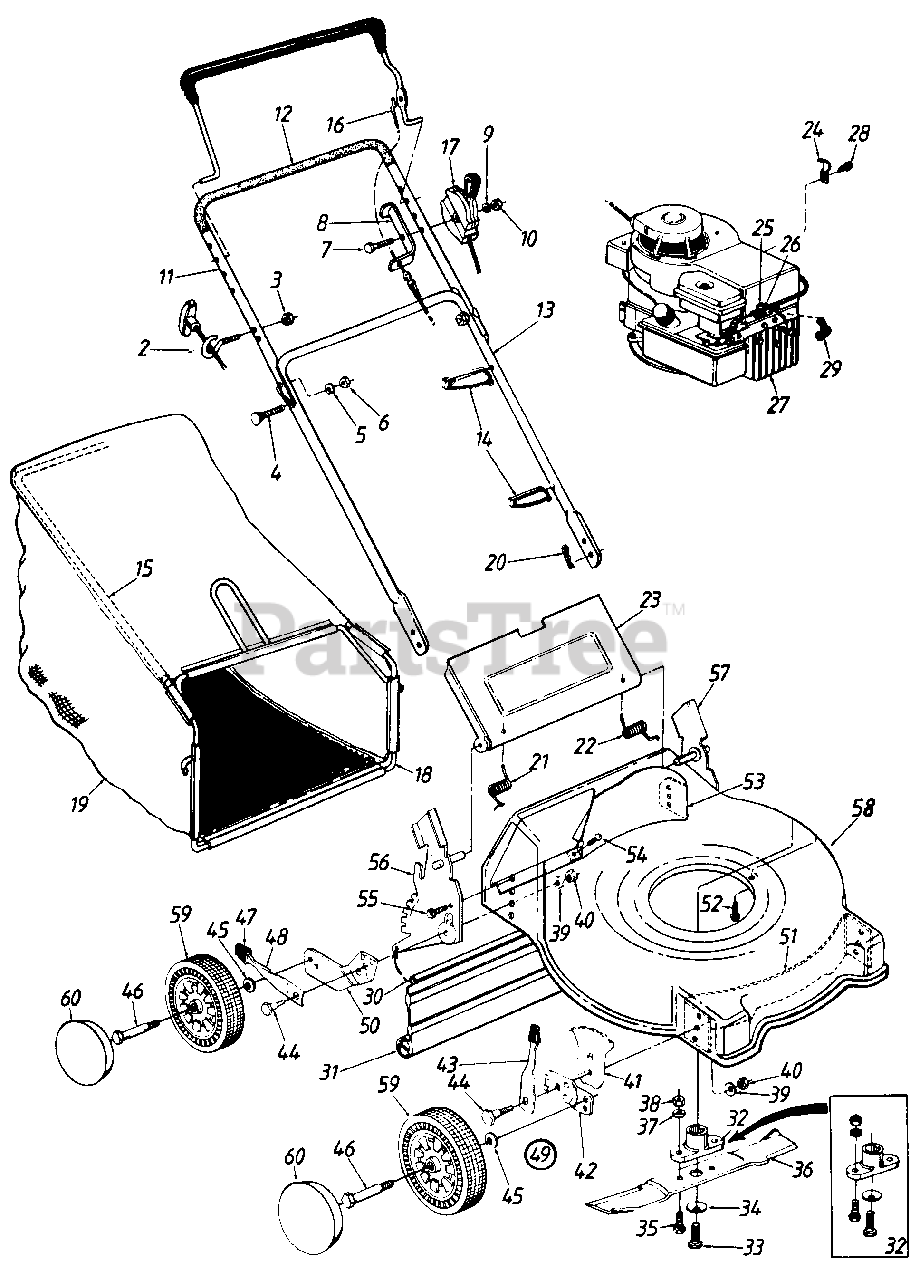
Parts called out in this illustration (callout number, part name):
2	Rope Guide Bolt
3	Hex L-Nut 1/4-20 Thd.
4	Curved Carr. Bolt 5/16-18 x 1.38" Lg.
5	L-Wash. 5/16" I.D.
6	Hex Nut 5/16-18 Thd.
7	Hex Bolt 1/4-20 x 1-7/8" Lg.
8	Cable Brkt.
9	Spr Wash. 1/4 I.D.
10	Hex Nut 1/4-20 Thd.
12	Foam Grip
13	Lower Handle
14	Cable Tie
16	Control Cable-36"
17	Throttle Control Ass'y. Comp.
20	Int. Cotter Pin 5/16" Dia.
21	Door Spring-R.H.
22	Door Spring-L.H.
26	Hex AB-Tap Scr. #8 x .5" Lg.
27	Engine
28	Hex B-TaP Scr. #10 x .38" Lg.
29	Spark Plug Boot
30	Wire Rod
31	Rear Flap
32	Blade Adapter Kit
33	Hex Bolt 3/8-24 x 1.5" Lg.
34	Bell-Wash. .39" I.D.
35	Hex Bolt 3/8-24 x 1 Lg.
36	21" Blade
37	L-Wash. 3/8" I.D.
38	Hex Nut 3/8-24 Thd.
39	Bell-Wash. .39" I.D. x 1.38"
40	Hex Nut 3/8-16 Thd.
41	Height Adj. Plate
43	Spring Lever Ass'y. w/Knob
44	Shld. Bolt .5" Dia. x .357"
45	Bell-Wash. .38" I.D. x .88" O.D.
46	Axle Bolt
47	Spring Lever Knob
49	Height Adj. Ass'y. Comp.-R.H.
54	Torx Bolt 1/4-20 x .5" Lg.
55	Hex L-Wash. Hd. AB-Tap Scr. 1/4 x .62" Lg.
56	Handle Brkt. Ass'y.-R.H.
57	Handle Brkt. Ass'y.-L.H.
60	Hub Cap
